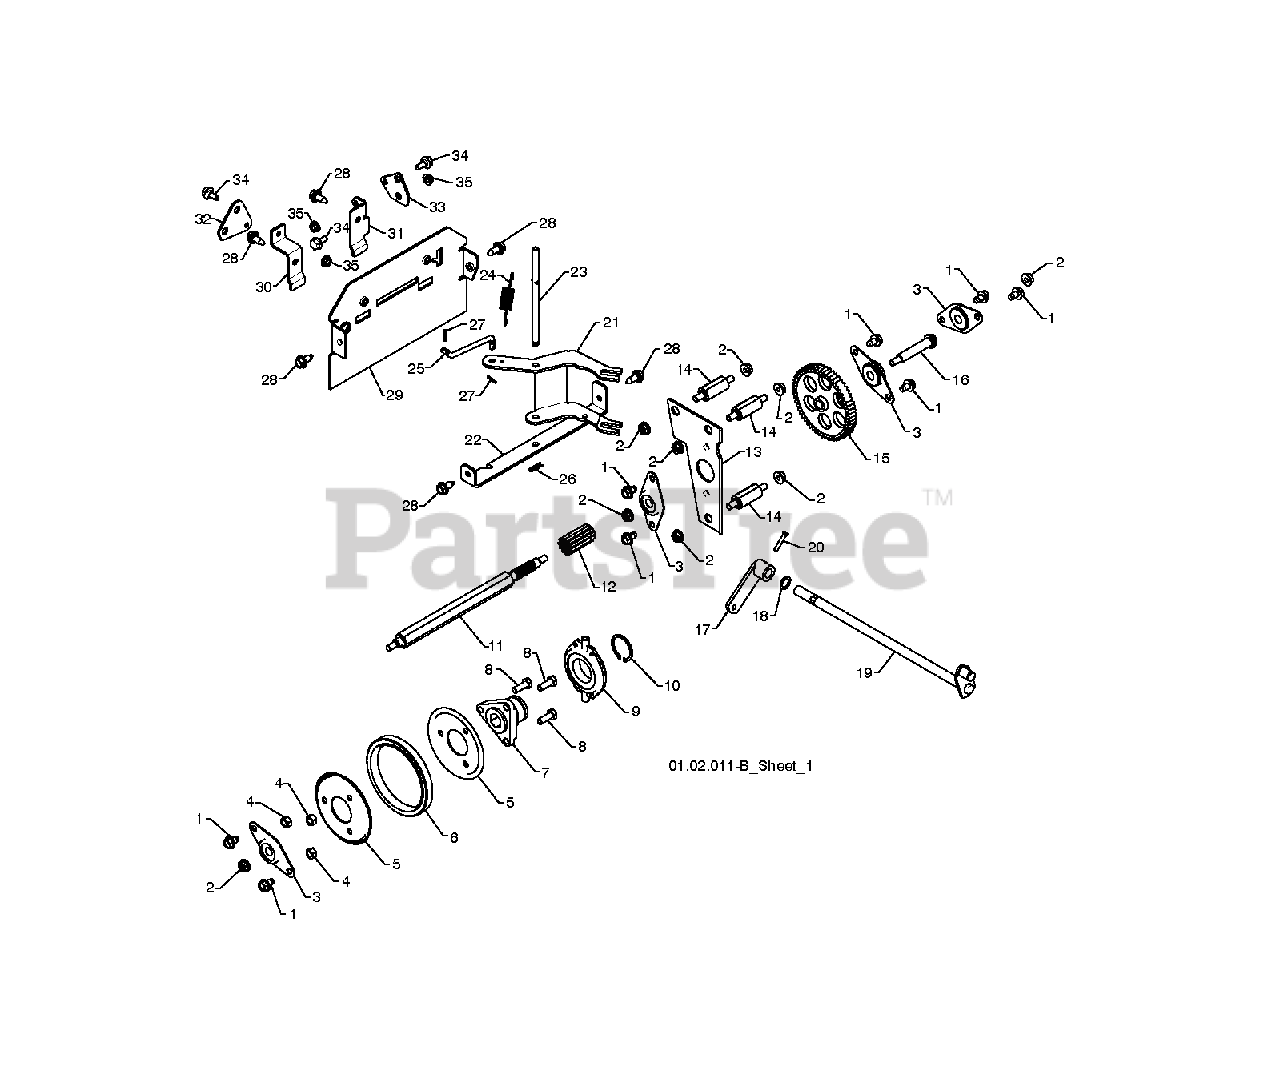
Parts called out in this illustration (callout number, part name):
2	NUT, LOCK 5/16-18
3	BEARING, FLANGE
4	NUT.CENTERLOCK.5/16-
5	PLATE.RUBBER.WHEEL.BLACK
6	RING, RUBBER WHEEL
7	HUB, RUBBER WHEEL
9	TRUNNION BEARING ASSY
10	RETAINING RING
11	SHAFT.HEX.LONG
13	PLATE.AUXILIARY.
14	SPACER, PLATE
15	GEAR, INTERMEDIATE
16	SHAFT, AUXILIARY
17	ARM, AUGER CONTROL
18	THRUST WASHER
19	CONTROL.SHAFT.ASM
21	RP SHIFTER LEVER
22	BRACKET.SHIFT.PIVOT.BLACK
25	LINK, SPEED CONTROL
26	RETAINER CLIP PM
27	RETAINER CLIP
28	BOLT.HEX.HD.WASHER.5/16-18X.75
29	PLATE.REAR.SNOW.PNT
30	RP BRACKET.SHIFTER.PLATE
31	BRACKET.CLUTCH.PLATE
32	PLATE.SHIFTER.YZ
33	PLATE.CLUTCH.
34	BOLT.SHOULDER.3/X.25
35	NUT.HEX.FLANGE.1/4
